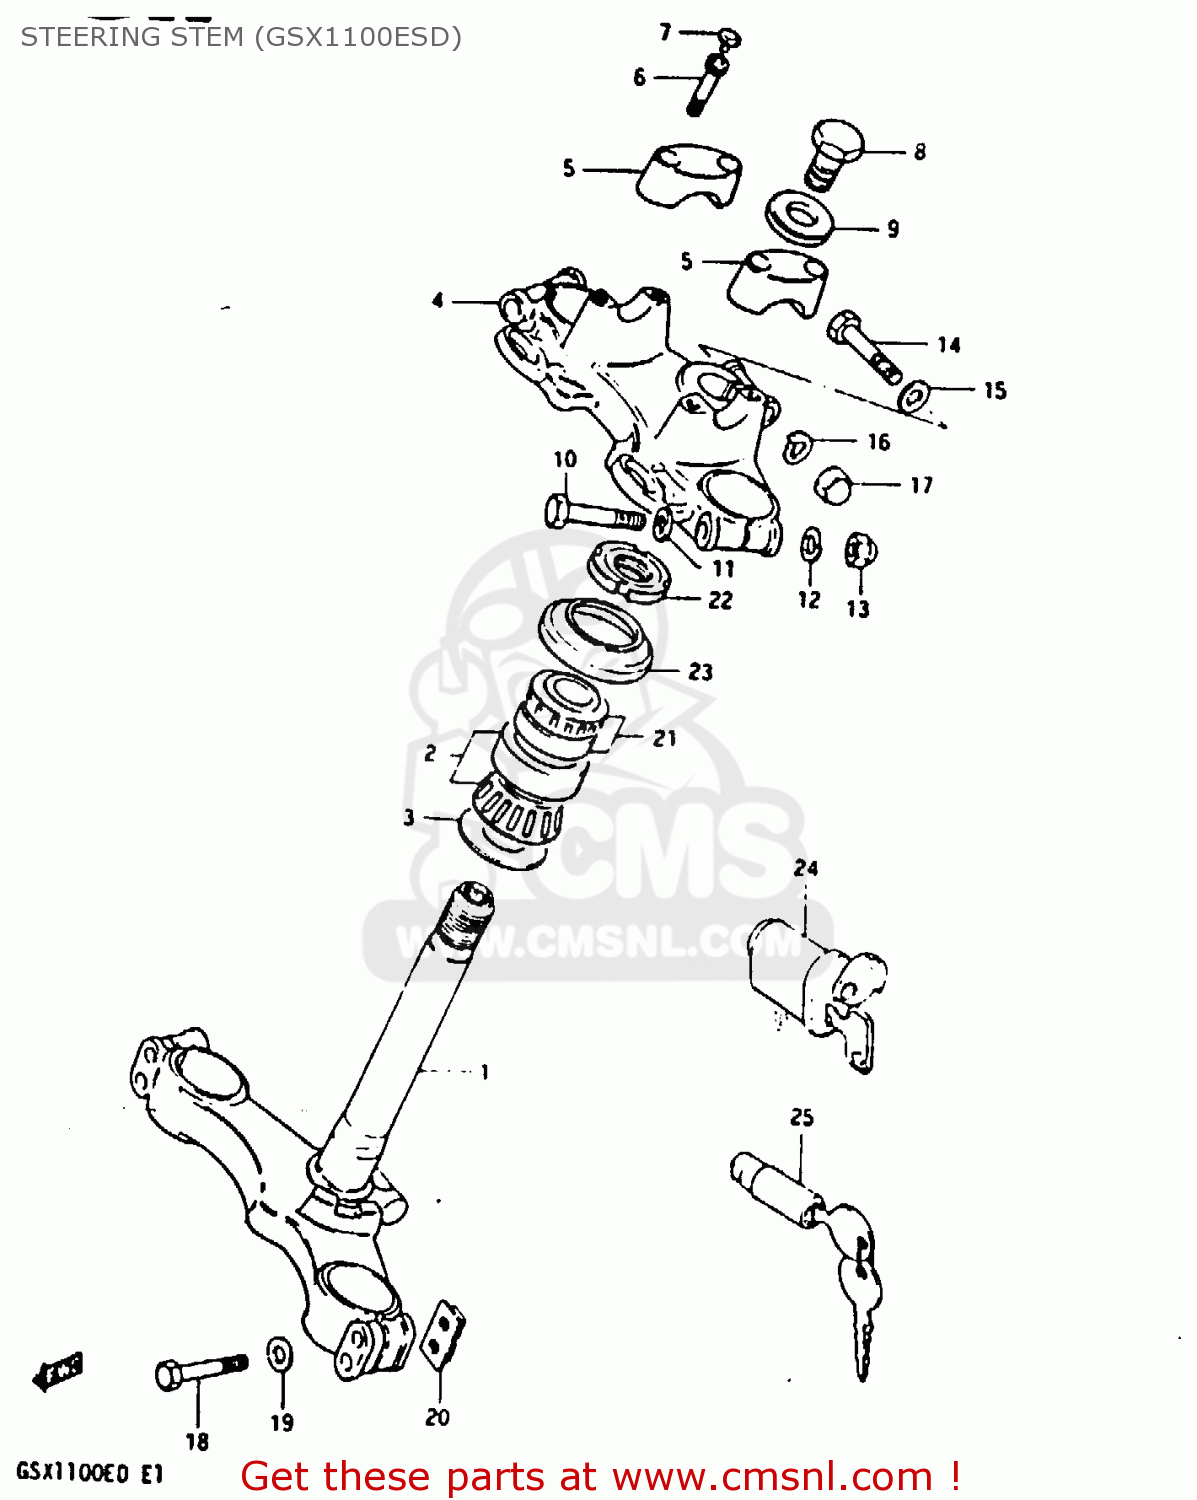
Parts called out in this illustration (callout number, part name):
1	STEM,STEERING
2	BEARING
3	WASHER,THRUST
4	HEAD,STEERING STEM
5	HOLDER,HANDLEBAR
6	BOLT
7	CAP(OD:14.5)
8	NUT,STEM HEAD
9	WASHER,STEERING STEM B
10	BOLT 10X55
11	WASHER 10MM
12	LOCK WASHER
13	NUT 10MM
14	BOLT
15	WASHER
16	LOCK WASHER
17	NUT,M8X1.25X12
18	BOLT 8X55
19	WASHER
20	NUT,FR FORK INNER TUBE
21	TAPER,ROLLER BEARING
22	NUT,STEERING STEM
23	DUST SEAL,STEERING UPR
